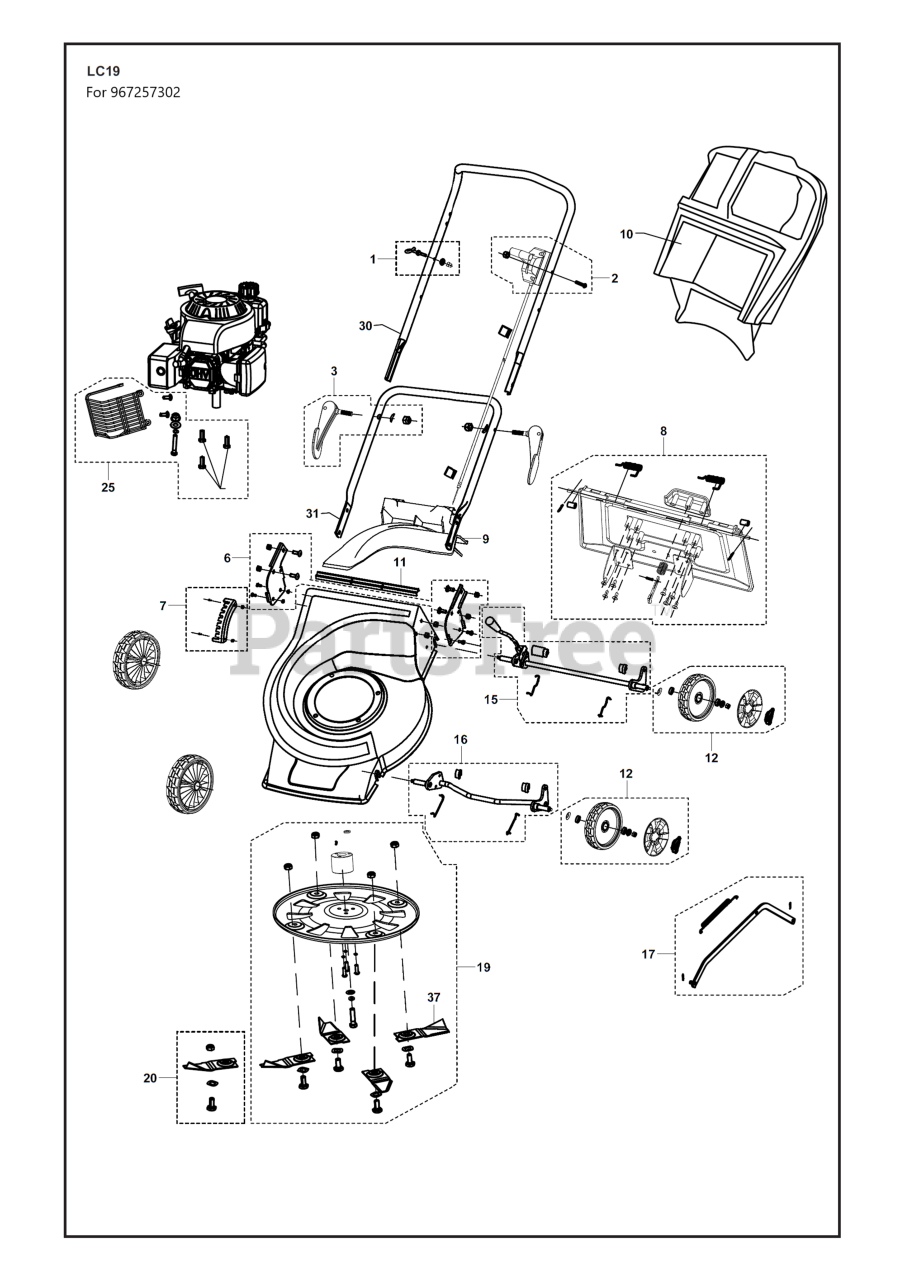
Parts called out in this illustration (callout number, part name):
2	CLIP-BODY-TRIM
3	PIN, BOW TIE LOCKING - .072
4	SCREW,M6,TORX,INTERLOCK,THREAD
5	PANEL, COWL, PS, RTHWHD
6	PANEL, COWL, DRV, RTHWHD
7	WELDMENT, HINGE, HOOD
8	PROP, HOOD
9	SCREW, TUFLOK PANEL, 1/4
10	Hood, Design B, Moff
11	PANEL, COWL, UPPER, B,MOFF
13	CLIP-BODY-TRIM
14	PIN, BOW TIE LOCKING - .072
15	SCREW,M6,TORX,INTERLOCK,THREAD
16	PANEL, COWL, PS, ORANGE
17	PANEL, COWL, DRV, ORANGE
18	WELDMENT, HINGE, HOOD
19	PROP, HOOD
20	SCREW, TUFLOK PANEL, 1/4
21	HOOD, DESIGN B, ORANGE
22	PANEL, COWL, UPPER, B, ORANGE
24	CLIP-BODY-TRIM
25	PIN, BOW TIE LOCKING - .072
26	SCREW,M6,TORX,INTERLOCK,THREAD
27	PANEL, COWL, PS, OLIVE GREEN
28	PANEL, COWL, DRV, OLIVE GREEN
29	WELDMENT, HINGE, HOOD
30	PROP, HOOD
31	SCREW, TUFLOK PANEL, 1/4
32	HOOD, DESIGN B, OLIVE GRN
33	PANEL, COWL, UPPER, B, OLV GRN
